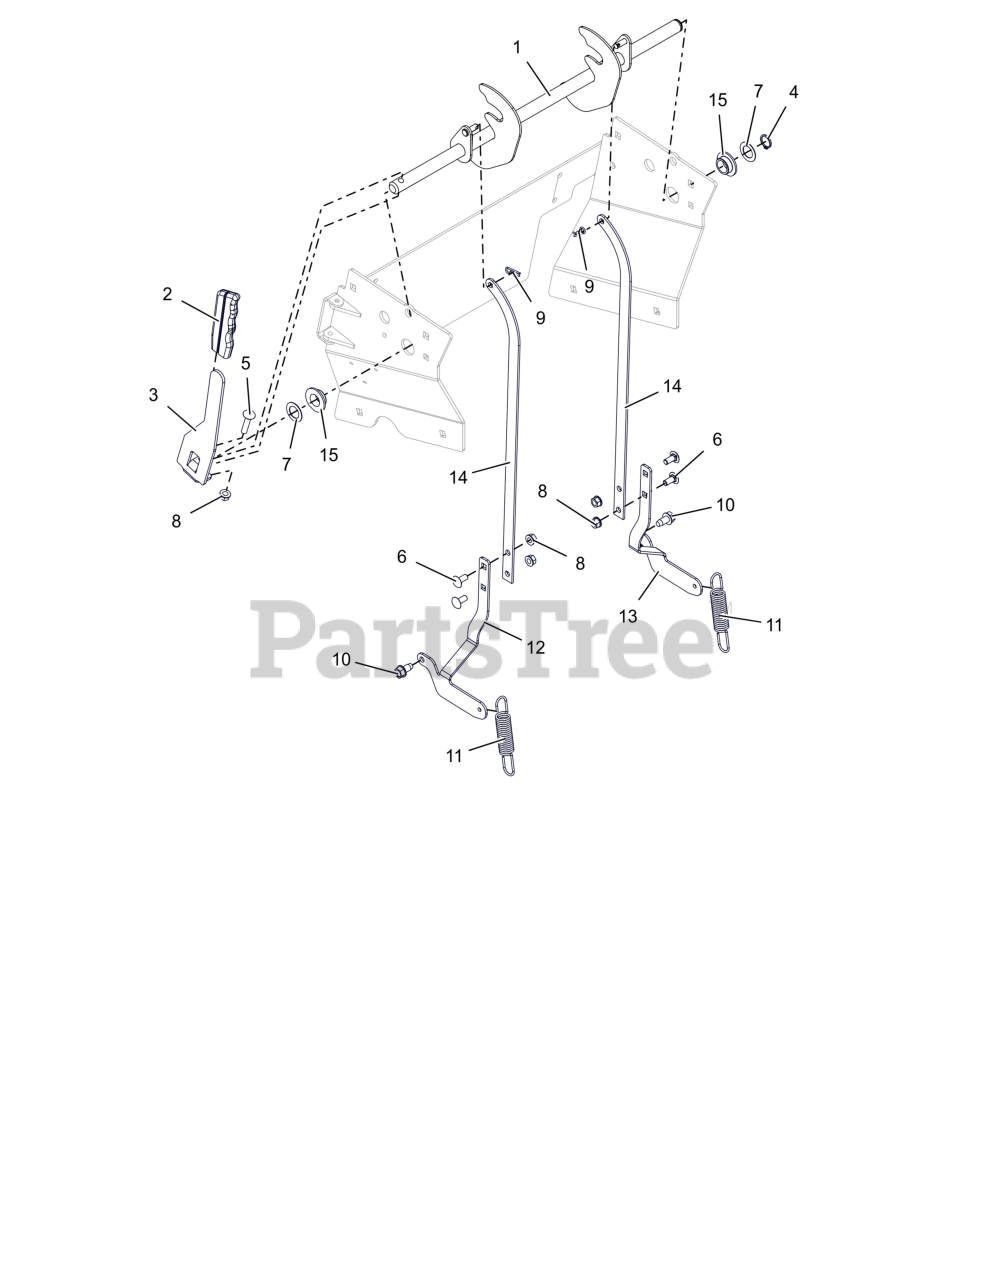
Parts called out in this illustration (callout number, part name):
1	WMT- NARROW PARK BRAKE
2	GRIP, PARKING
3	HANDLE, PARK BRAKE (BLACK)
4	RG-RTNG-EXT .689X.078
5	BLT,RHSN .31-18X1.50 G5 ZCC
6	BLT, RHSSN.31-18X.750 G5 ZCC
7	WSHR-FL-STL 0.76X1.225X0.032 ZCC
8	NUT,LK-CTR-FLG .31-18 GF ZCC
9	PIN, HAIR #213 .08X1.19 ZCC
10	SCR,TAP .375-16X.75 HWH TR ZCC
11	SG-TENS .105X.85X5.00 WLD 40
12	LINKAGE-PARK BRK LOWER RH(BLK)
13	LINKAGE-PARK BRK LOWER LH(BLK)
14	LINKAGE- PARK BRAKE
15	BSHG, FLANGED .762 X 1.48 X .44 IGLIDER
